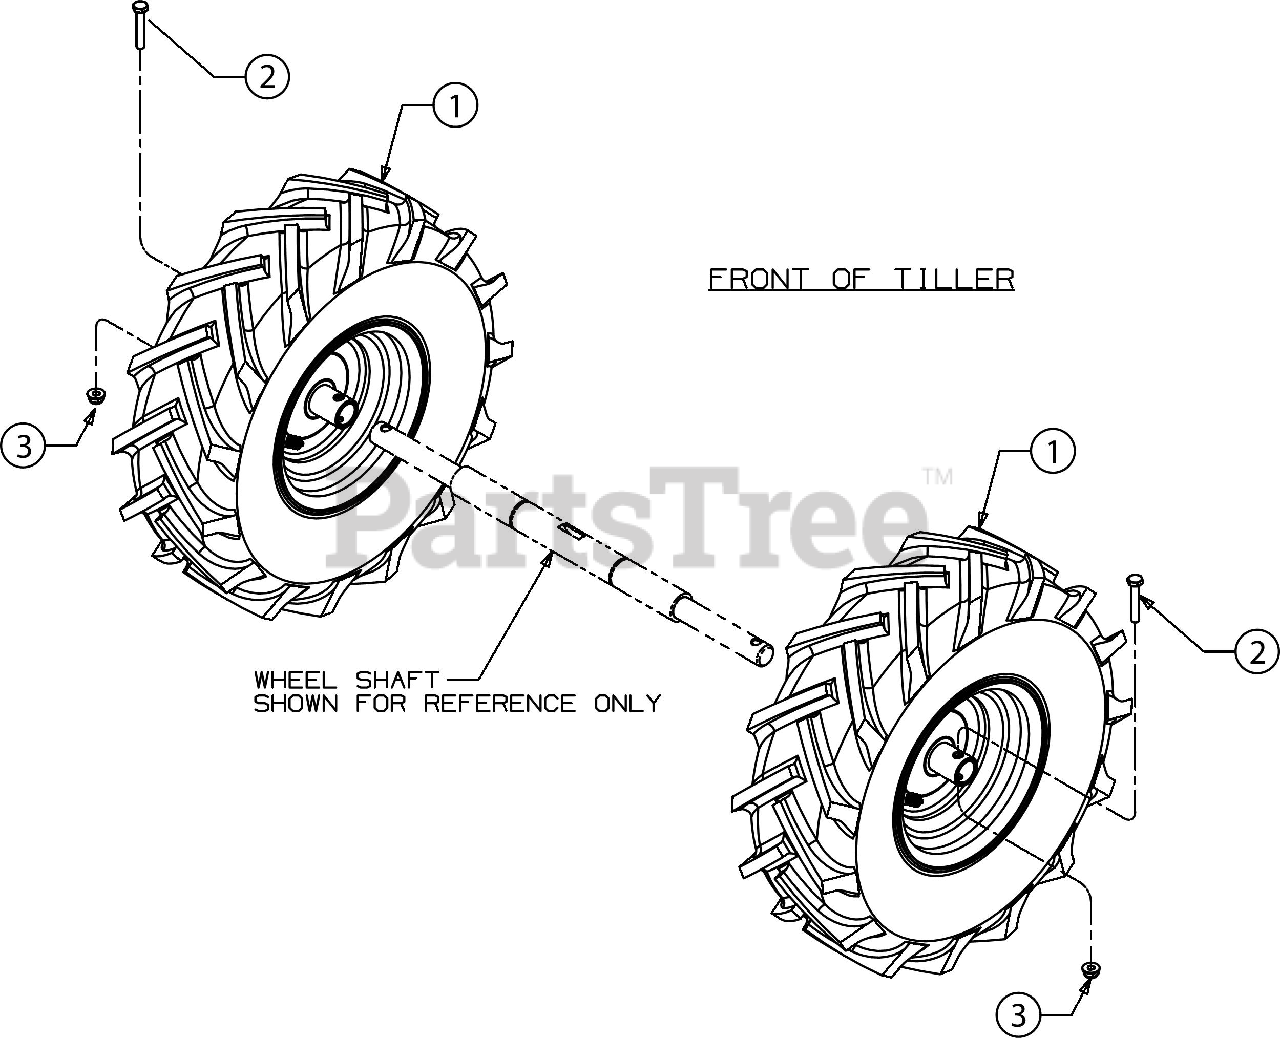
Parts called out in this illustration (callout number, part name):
1	WHEEL ASSEMBLY (14 x 4.5-6) (BEIGE)
1	AG TIRE 14 x 4.5-6
1	RIM ASSEMBLY (6 x 3.25) (BEIGE)
1	TUBELESS VALVE
2	SCREW 1/4-20 x 1.50 GR8
3	FLANGE LOCK NUT
